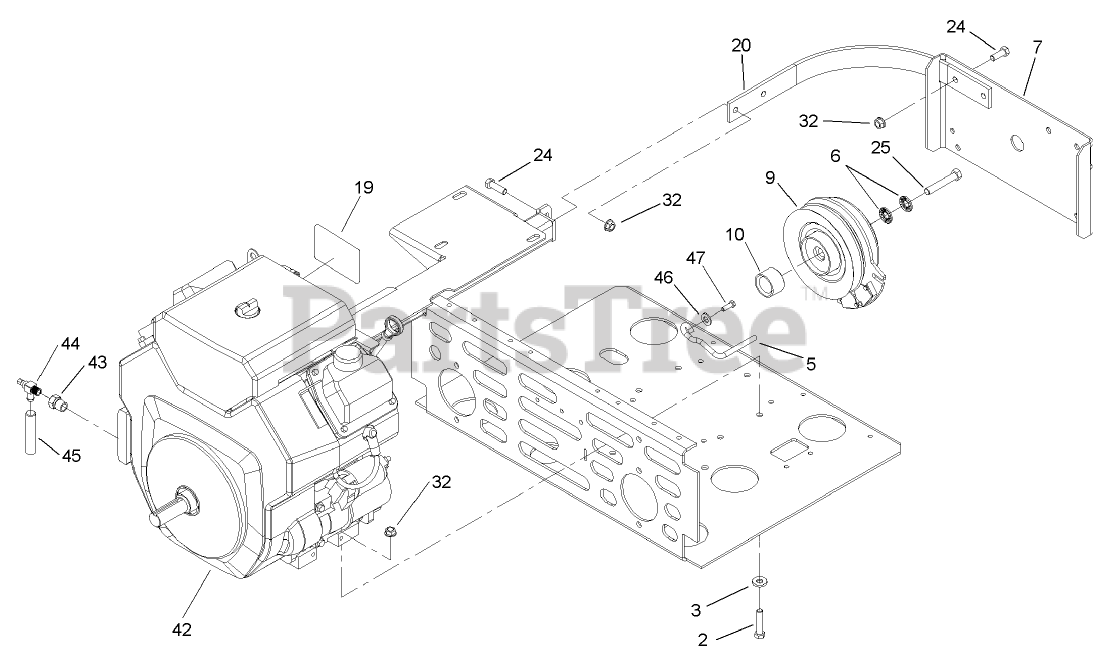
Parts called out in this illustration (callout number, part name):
2	SCREW-HH
3	WASHER-BELLEVILLE
5	ROD-BELT
6	WASHER-SPRING
7	GUARD-CLUTCH
9	Clutch
10	SPACER-CLUTCH
20	BRACKET-GUARD, TOP
24	SCREW-HH
25	SCREW-HH
32	NUT-HHF, WHIZ
43	Adapter
44	Valve-Drain, Oil
45	HOSE-DRAIN, OIL
46	WASHER-FLAT
47	SCREW
